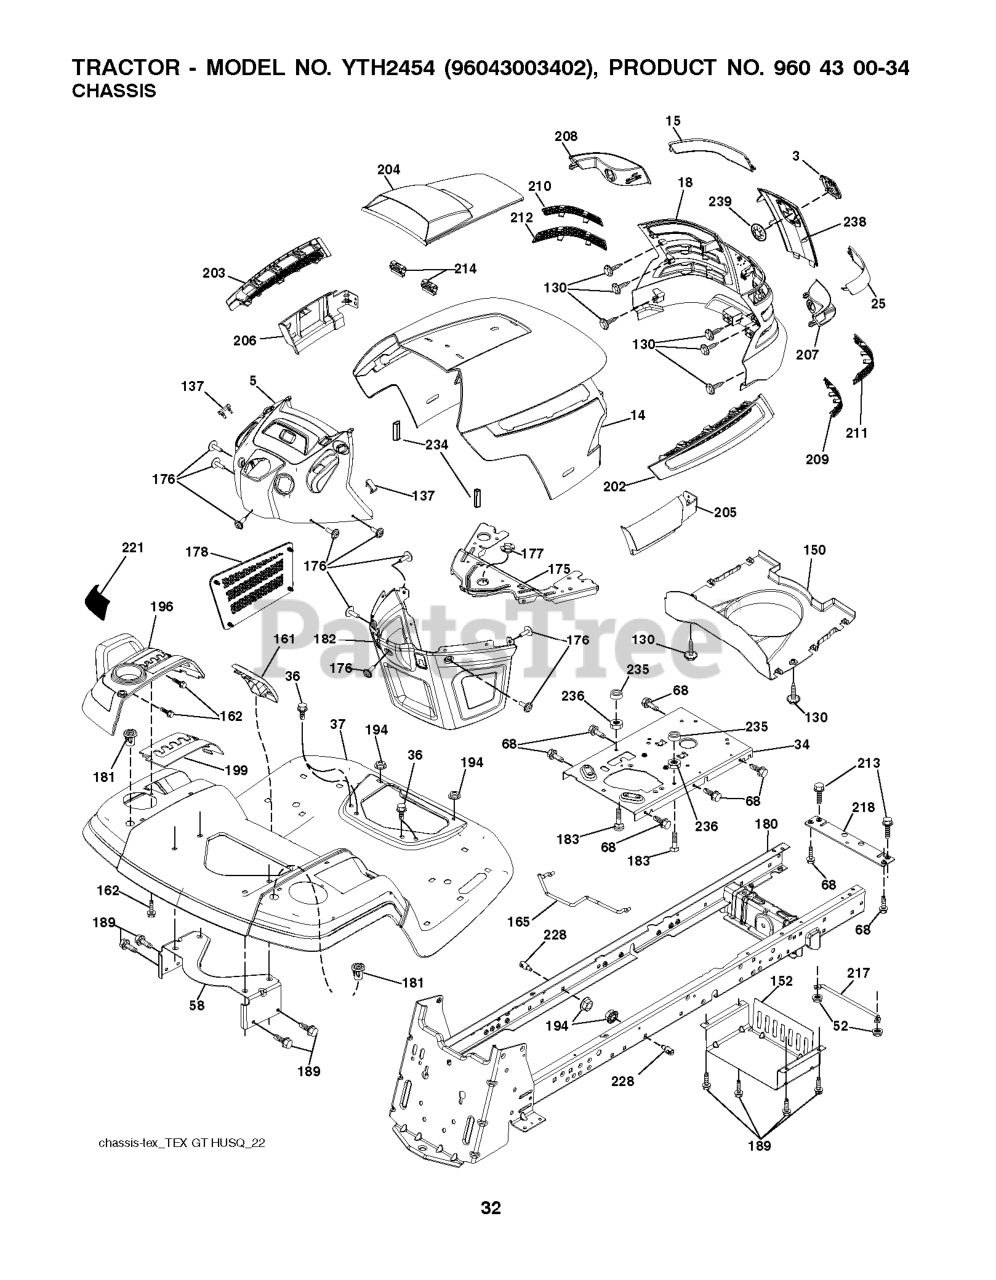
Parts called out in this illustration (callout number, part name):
3	RP LOGO
5	DASH.ASM.HUSQ.GT.E.RECT.W/CK
14	HOOD
15	LENS.LH.TEX.GT.HUSQ.CL
18	GRILL.ASM.HUSQ.TG/CRD.W/TRIM
25	LENS.RH.TEX.GT.HUSQ.CL
34	PLATE.ENGINE.WELDED.CHASSIS
36	SCREW 5/16"
37	FENDER.PNT.TX.GT.CH/FW.ORANGE
52	LOCKNUT
58	BRKT.SUPPORT.FNDR/TANK
68	Screw 5/16-18 x 1/2 Hex, Self Tapping 5/16-18 x 1/2
130	SCREW.#10 X 0.750.BOS
137	BUMPER DASH
150	AIR.DUCT.HOOD.TEX.GT.HUSQ
152	SHIELD.BROWNING.W/TEX
161	CONSOLE.FUEL.WINDOW.HU
162	SCREW.HI-LO.CONSOLE
165	SUPPORT.TANK.REAR.W/TEX
175	PLATE.CROSSMEMBER.HUSQ
176	SCREW.#10-24X5/8.RN.QU
177	BUSHING, STEERING
178	CARGO.ASM.NET.TXGT.W/C
180	CHASSIS.GT.SLOPED.DRAWBAR.
181	BUSHING.MNT.FEND.CRGO.
182	DASH.LOWER.COMMON.12V.ADAPTOR
183	BOLT.5/16-18X1-1/4 FULL.THREAD
189	SCREW
194	NUT LOCK HEX FLANGE 5/16-18
196	RP CONSOLE.ASM.DECKLFT.W/
199	PLATE.DECK.LIFT.HUSQVARNA.GT
202	VENT.SIDE.HOOD.HUSQ.RH.GREY
203	VENT.SIDE.HOOD.HUSQ.LH.GRAY
204	VENT.ASM.TORPHD.HUSQGT.LOGO.CL
205	SKIRT.HOOD.SIDE.HUSQ.RH.GREY
206	SKIRT.HOOD.SIDE.HUSQ.LH.GREY
207	BEZEL.RH.TEX.GT.HUSQ
208	BEZEL.LH.TEX.GT.HUSQ
209	INSERT.HEX.GRILL.HUSQ.GREY
210	INSERT.HEX.GRILL.HUSQ.
211	INSERT.HEX.GRILL.HUSQ.
212	INSERT.HEX.GRILL.HUSQ.
213	BOLT
214	CLIP.RETAINER.TINNER.
217	ROD.PIVOT.HOOD
218	X-PIECE.HOOD.STOP.NON/
221	REFLECTOR.LH.TEX GT HU
228	STUD.FASTNER.W/ANTI-ROTATE
234	BUMPER.HOOD.TEX.HUSQVARNA
235	SPACER FENDER
236	NUT.CENTERLOCK.5/16-
238	TRIM.HUSQ.TG/CRD.SERVICE
239	NUT PUSH M
